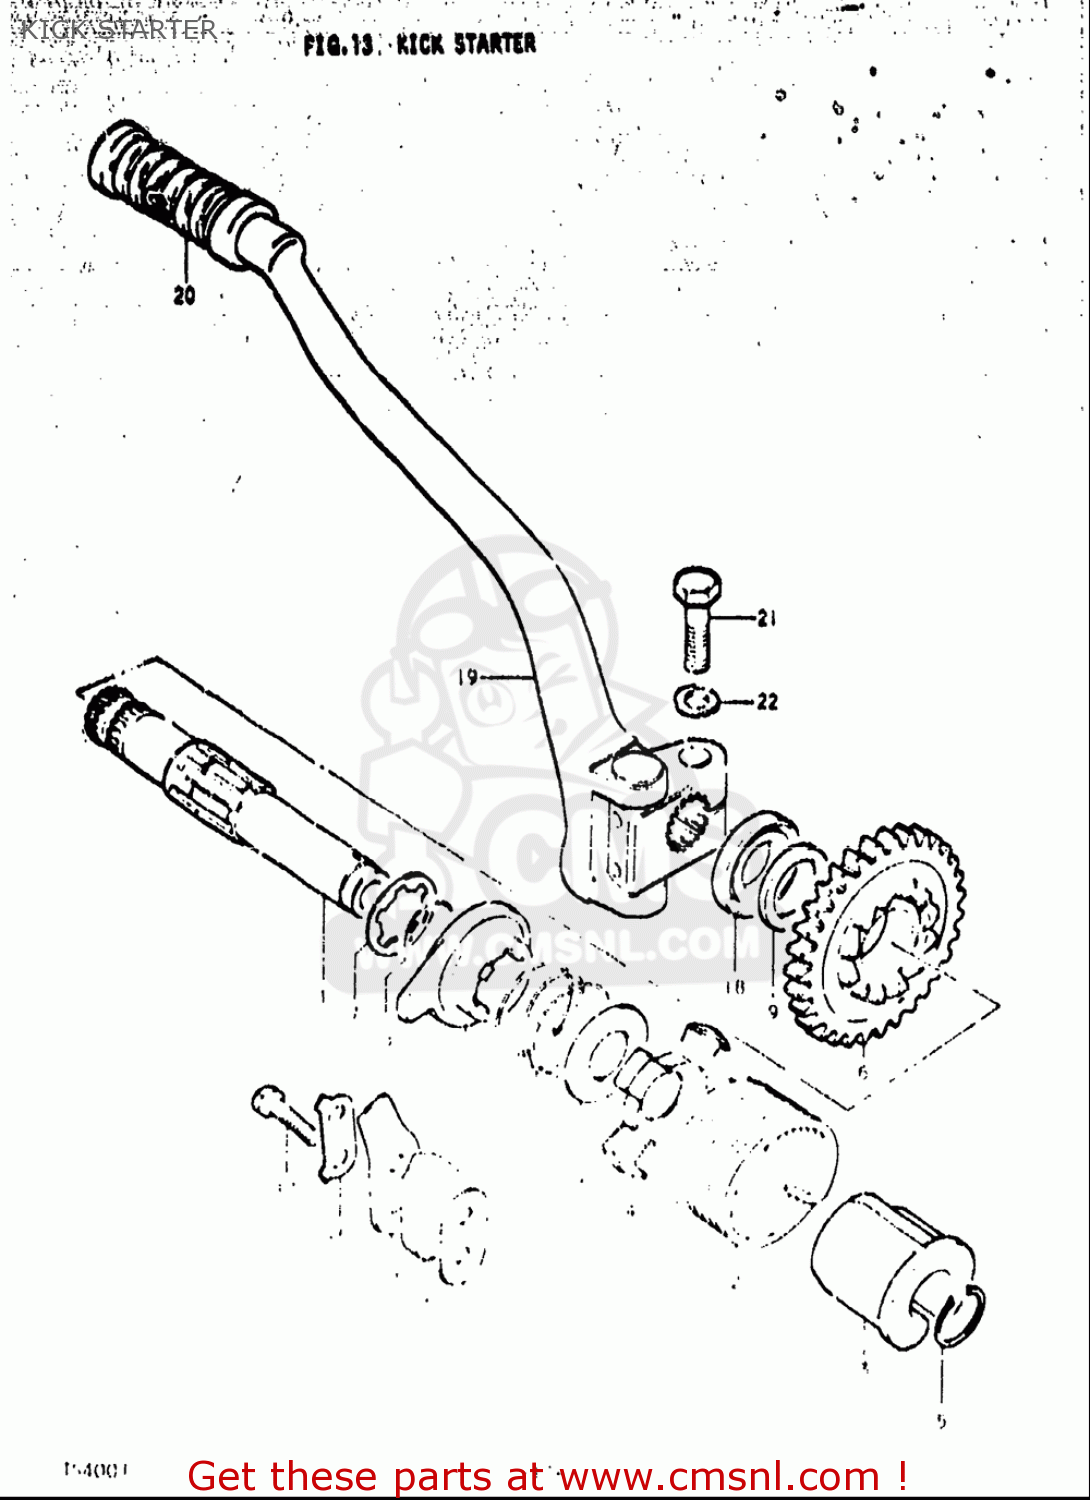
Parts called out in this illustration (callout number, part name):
2	SPRING
3	GUIDE,KICK SHAFT SPRING
4	HOLDER,KICK SHAFT SPRING
5	CIRCLIP
7	WASHER,LOCK
8	CIRCLIP
10	STARTER,KICK
11	SPRING
12	WASHER
17	BOLT
18	SEAL,OIL(20X37X7)
20	RUBBER,KICK STARTER PEDAL
21	BOLT
22	WASHER,LOCK
